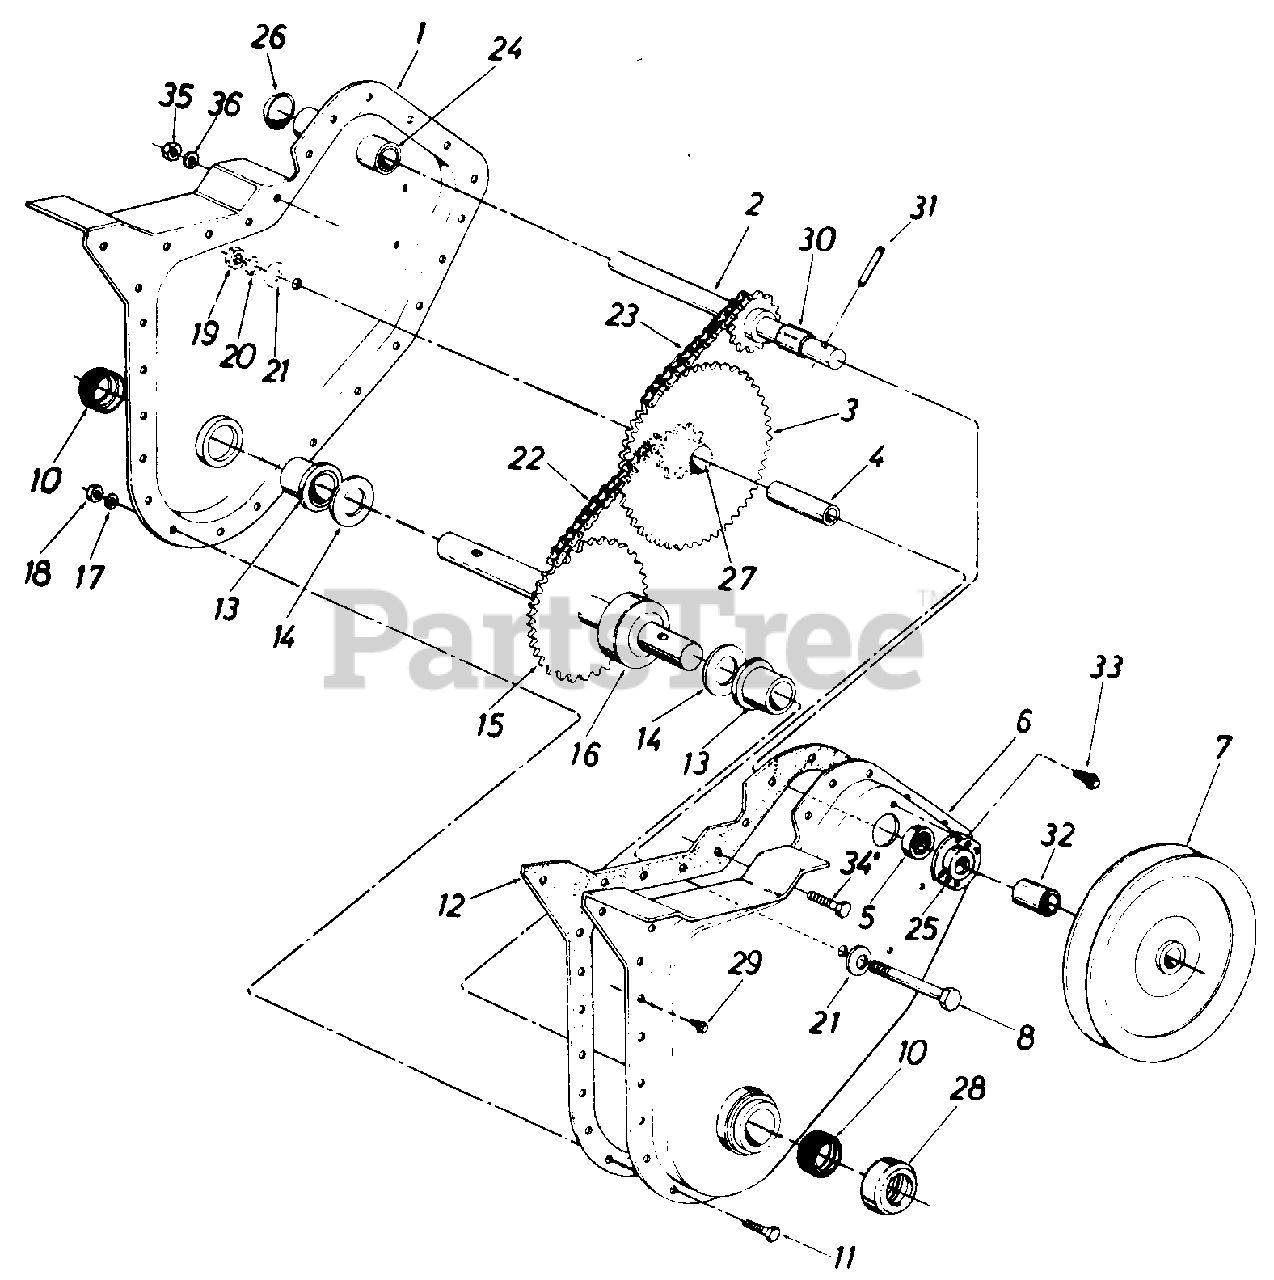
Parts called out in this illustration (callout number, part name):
1	Chain Case Ass'y.-R.H.
2	Input Shaft Ass'y.
3	Hub and Sprocket Ass'y.
4	Bearing Inner Race
5	Ball Bearing
6	Chain Case Ass'y.-L.H.
7	Pulley-Chain Case 51/2 x 1/2
8	Hex Bolt 3/8-24 x 2.50" Lg.*
10	Seal
11	Hex Bolt 1/4-28 x .625" Lg.*
12	Gasket
13	Flange Brg. .879 I.D.
14	Fl-Wash. .88 I.D. x 1.50 O.D. x .030
15	Tine Shaft Ass'y.
16	Spacer 7/8" I.D. x 2.0" O.D. x.68" Lg.
17	L-Wash. 1/4" Scr.*
18	Hex Nut l/4-28 Thd.*
19	Hex Ins. L-Nut 3/8-24 Thd.
20	L-Wash. 3/8" I.D.*
21	Bell-Wash. .406 I.D. x 1.130 O.D.
22	Chain #420-.50" Pitch x 38 Links
23	Chain #35-.375" Pitch x 50 Links
24	Bearing .62" I.D. x .813 O.D. x 1.31
25	Bearing Housing
26	Expansion Plug 13/16" Dia.
27	Bearing
28	Dust Cap
29	Hex Wash. Hd. Self-Tap Scr. 1/4-20 x .50" Lg.
30	Spacer .630 I.D. x .77 O.D. x 38" Lg.
31	Spring Pin Spiral 1/4" Dia. x 1-l/2" Lg.
32	Spacer .647 x 1.25"
33	Hex Wash. Hd. Self-Tap Scr. 1/4-20 x .38" Lg.
34	Hex Bolt 5/16-18 x .75" Lg.
35	Hex Nut 5/16-18 Thd.
36	L-Wash. 5/16" I.D.*
